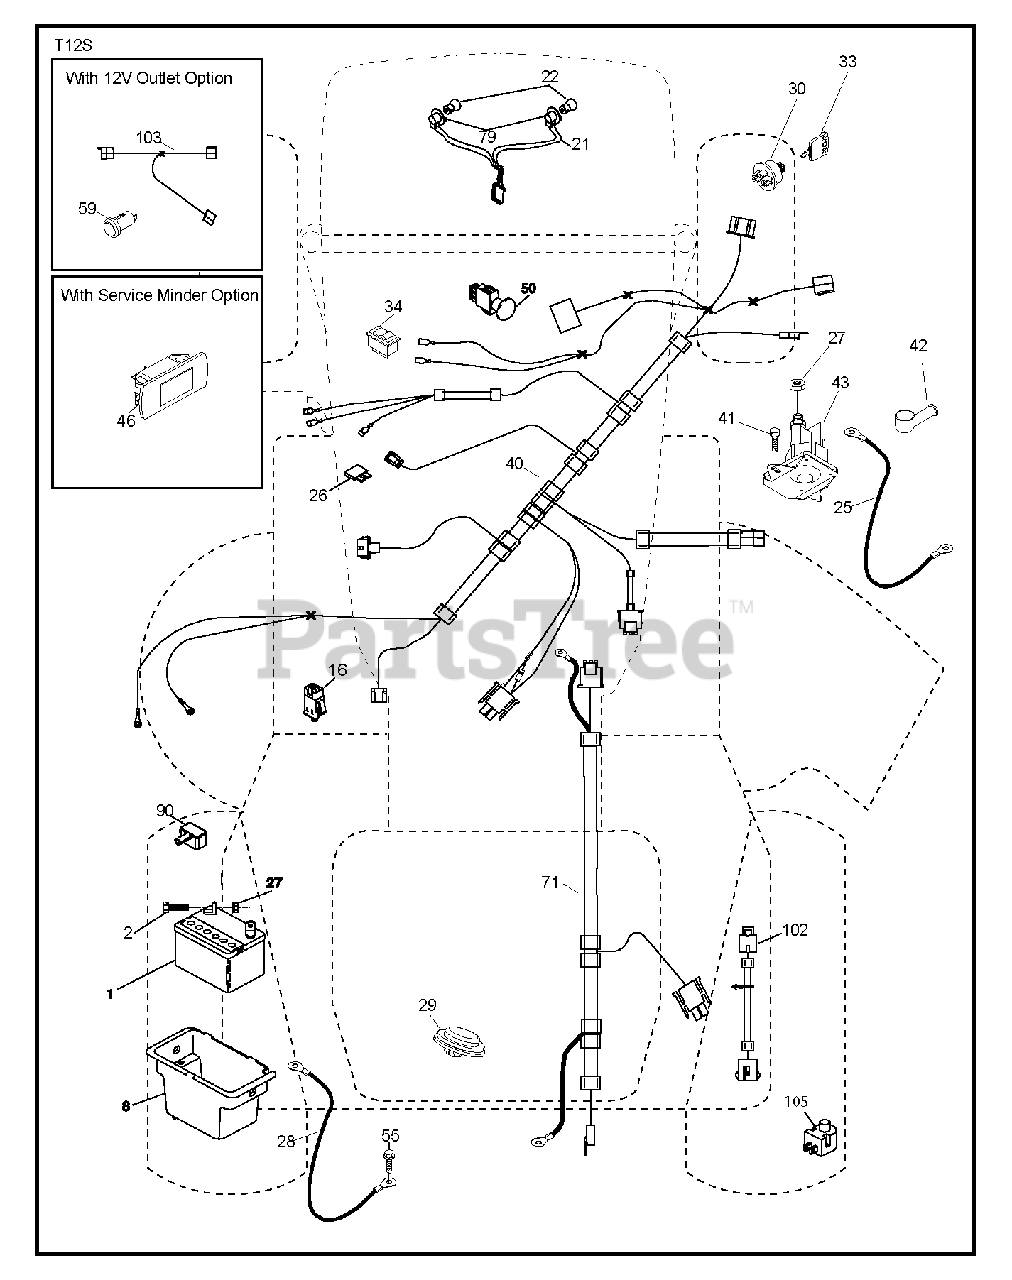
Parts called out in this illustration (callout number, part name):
1	Battery, Dry 30 Amp
2	BOLT.HEX.1/4.X.3/4.DICHROMATE
8	BOX.BATTERY.MNT.REAR.L
16	SWITCH INTERLOOK PUSH-IN
21	HARNESS.LIGHT W/4152J BULBS
25	CABLE.STARTER.6GA.BL/RED.14.
26	FUSE 20AMP
27	NUT
28	CABLE.BLACK.18"REAR.BA
29	SWITCH.SEAT.DELTA.OPC.
30	SWITCH.IGN.DELTA.W.LGH.ROS
33	KEY.CHAIN.BLISTER.PACK.GEN.INT
40	HARNESS.IGN.DASH.HUQ/P
41	SCREW
42	TERMINAL COVER
43	SOLENOID.W/BRASS.PLUNGER
46	RP GUAGE.SRVCMNDR.HRMTR.
50	RB PTO.SWITCH.8 TERMINAL.BLACK
55	SCREW 5/16"
71	HARNESS.IGN.CHASS.TEX.REAR.BAT
79	BULB HOLDER ASM.
90	COVER.TERMINAL.BATTERY
102	HARNESS PIGTAIL PCH TEX ROS
105	REVERSE SWITCH
